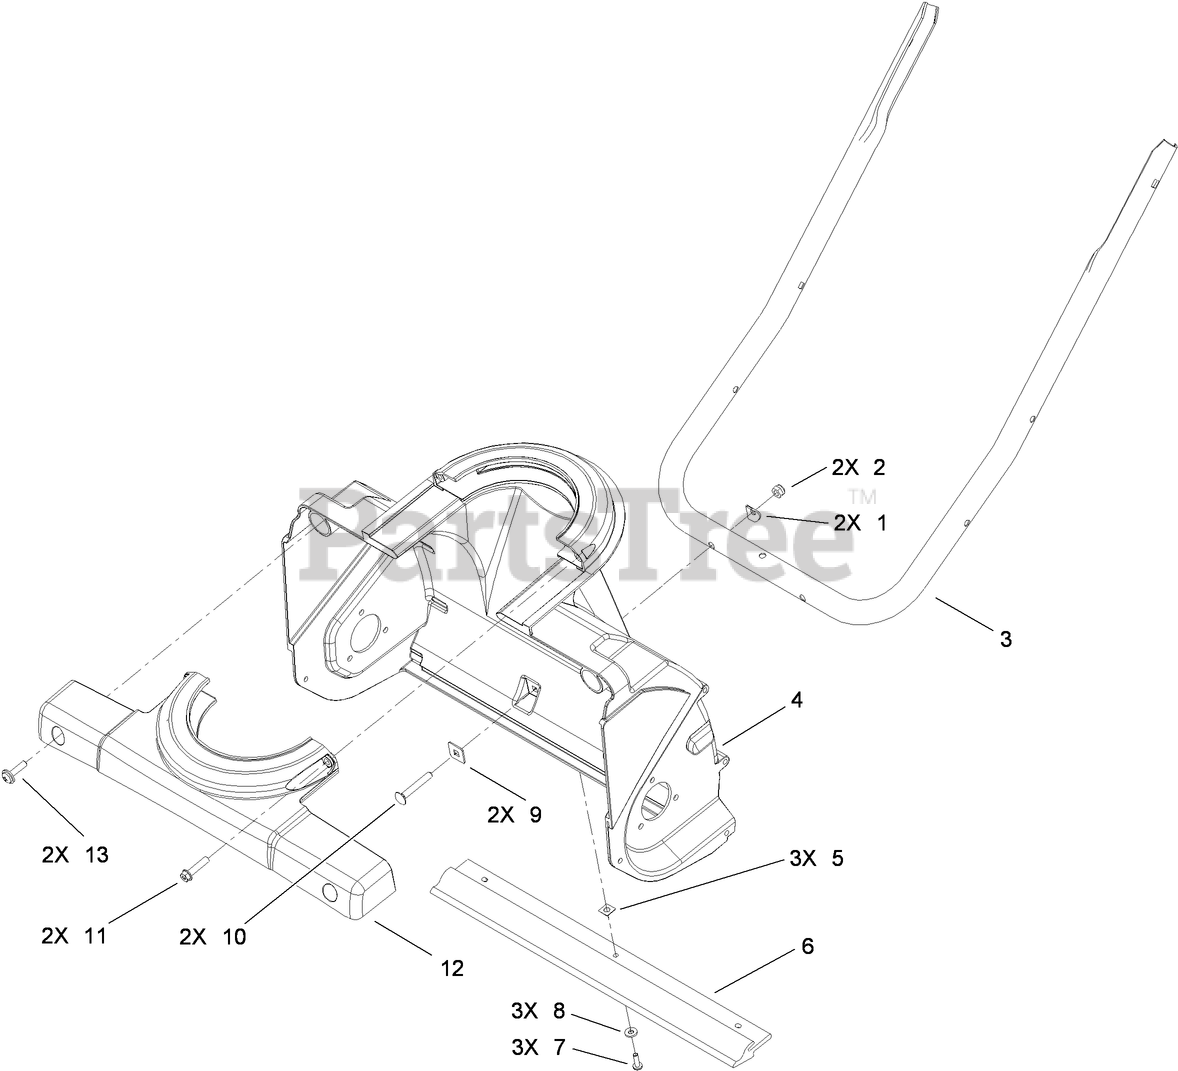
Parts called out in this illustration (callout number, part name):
1	WASHER
2	NUT-LOCK, NI
3	HANDLE-LOWER
4	HOUSING-LOWER
5	NUT-CLIP, U
6	SCRAPER
7	SCREW-HWHTF
8	WASHER-FLAT
9	WASHER-SQUARE
10	SCREW-CARR
11	SCREW-PLASTIC
12	RETAINER-CHUTE
13	SCREW-PPH
